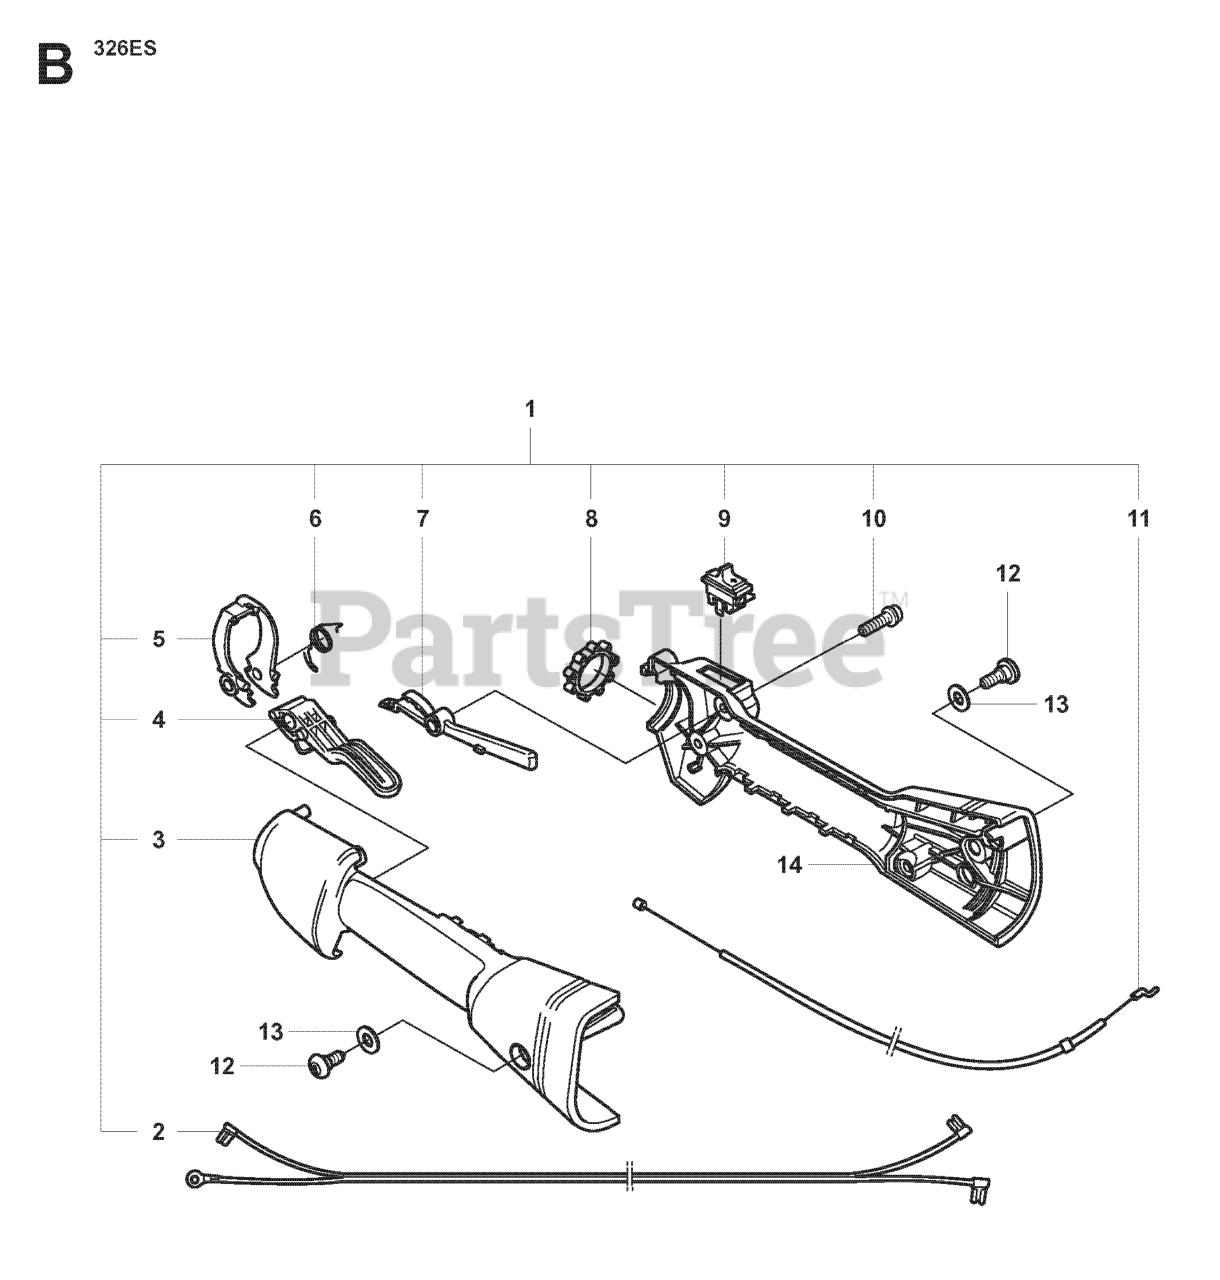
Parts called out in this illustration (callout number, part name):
2	SHORT-CIRCUIT CABLE
3	HANDLE HALF HSG LH
4	THROTTLE TRIGGER
7	THROTTLE LOCK
8	VIBRATION DAMPER
9	STOP BUTTON
11	THROTTLE CABLE
12	SCREW MT5X11
13	O-RING 8X1.6
14	HSG THROTTLE RH
